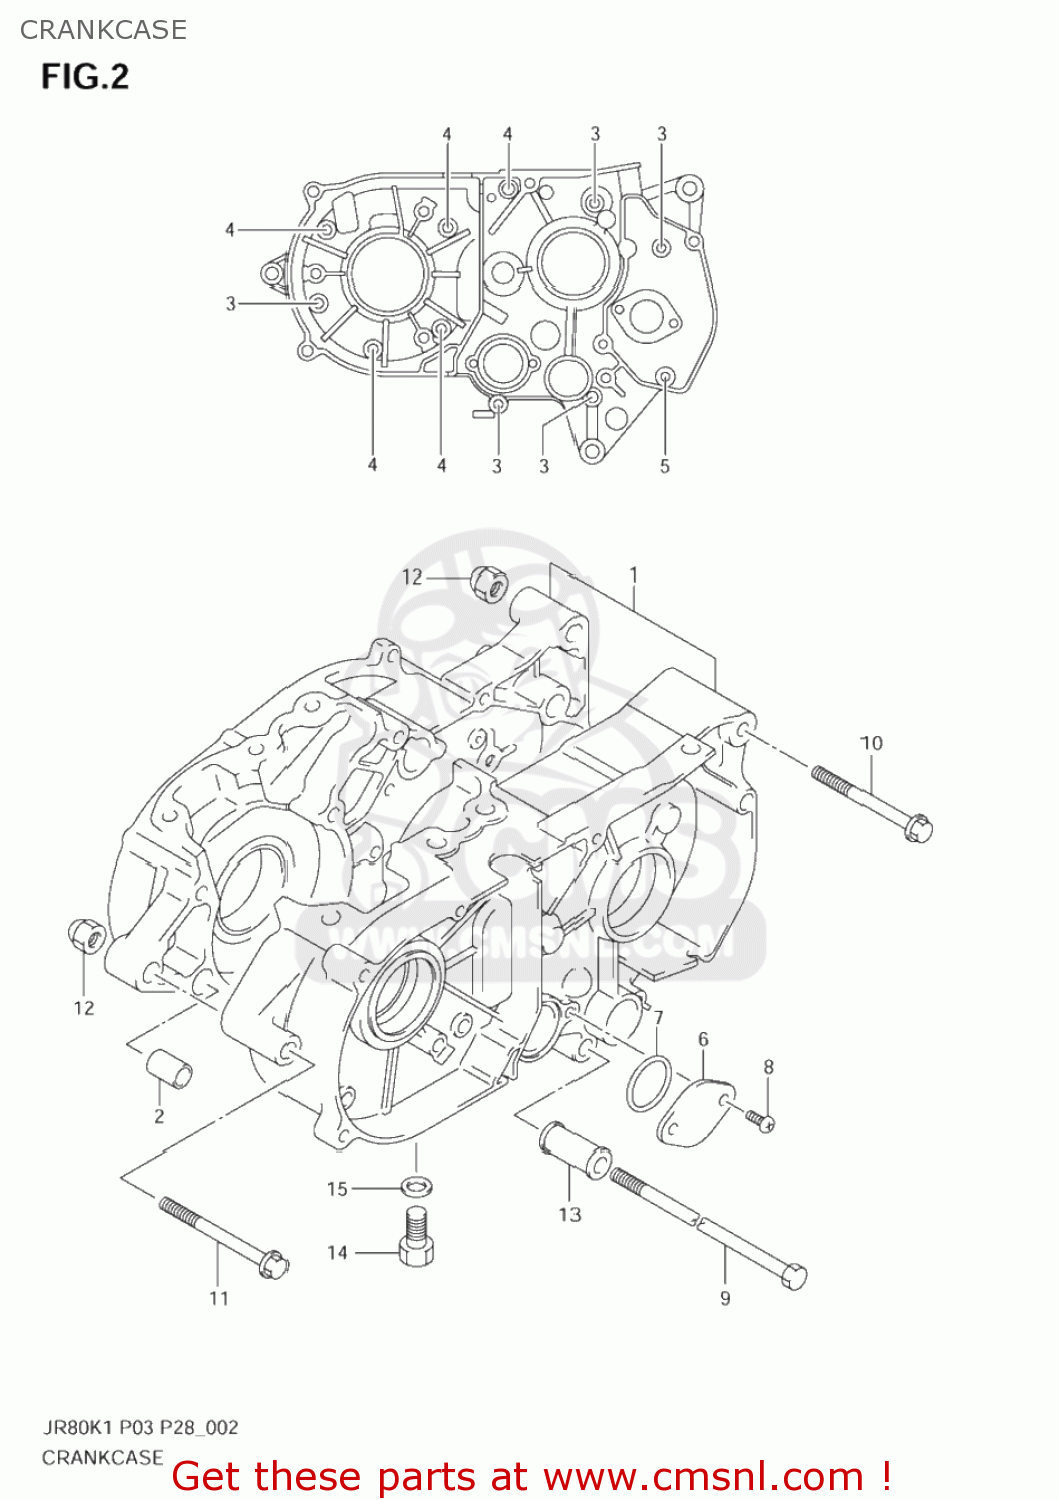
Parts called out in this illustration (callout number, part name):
1	CRANKCASE ASSEMBLY
2	PIN
3	SCREW
4	SCREW
5	SCREW
6	CAP,GEAR SHIFT CAM PIVOT
7	O RING(D:2.4,ID:26.2)
8	SCREW
9	BOLT(8X230)
10	BOLT(8X100)
11	BOLT(8X70)
12	NUT
13	SPACER,ENGINE MOUNT(L:46)
14	BOLT
15	GASKET(10X14X3.6) (NAS)
